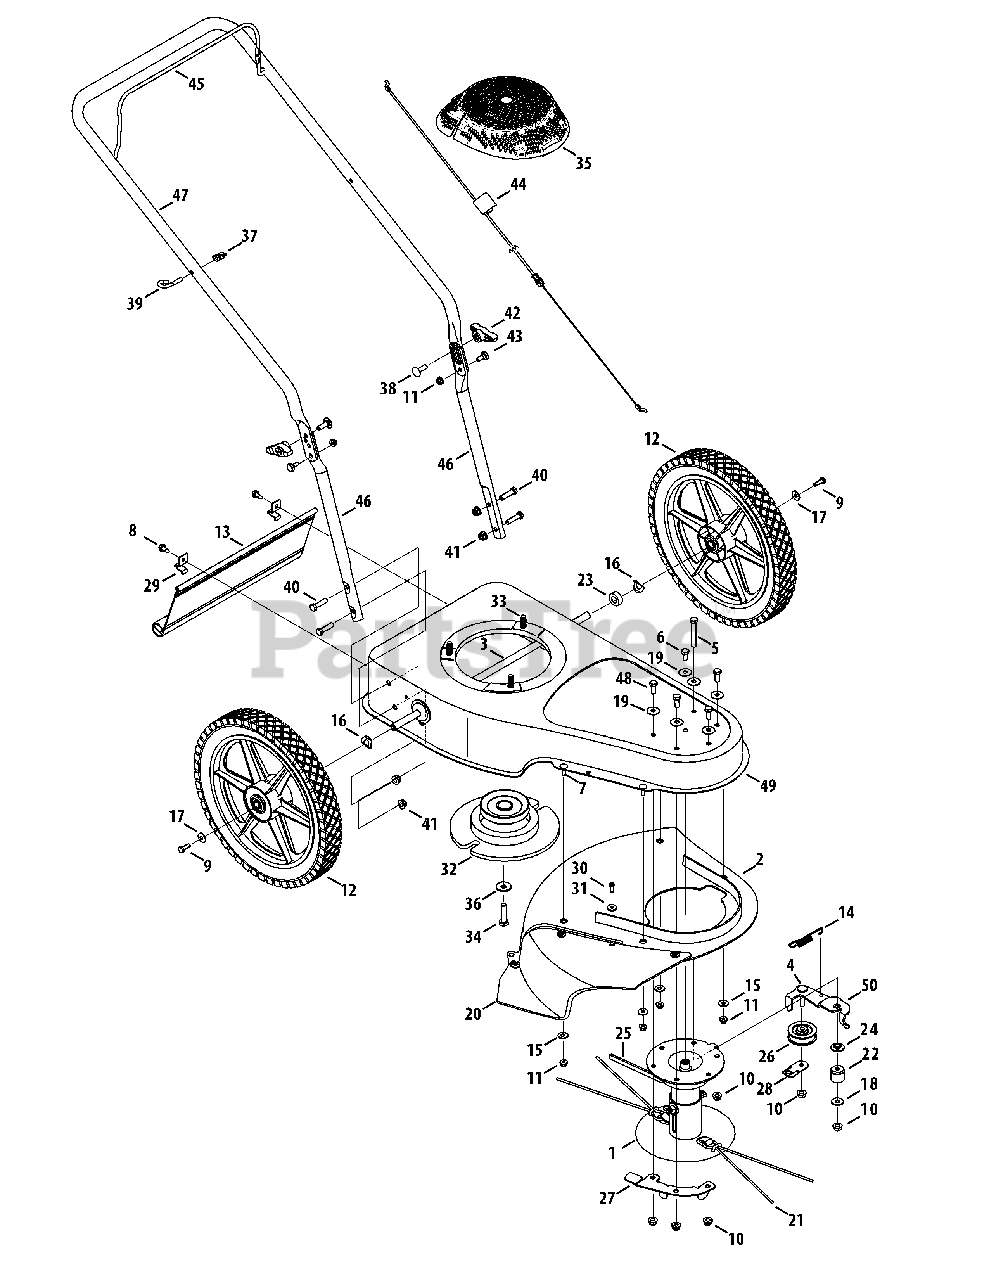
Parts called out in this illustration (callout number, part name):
1	Spindle Assembly
2	Deflector Assembly, Trimmer
3	Axle Assembly, Trimmer
4	Hex Cap Screw, 5/16-18 x 1.50
5	Hex Cap Screw, 5/16-18 x 2.25
6	Hex Screw, 5/16-24, .625, Gr5, Std
7	Screw, Carriage, 1/4-20, .75, Gr5
8	Screw, Self-tapping, 1/4-20 x .625
9	Hex Screw, 1/4-20, .75, Gr5, Std
10	Nut, Flange Lock, 5/16-18, GrF
11	Nut, Flange Lock, 1/4-20, GrF
12	Wheel, 14 x 1.75, Gray
13	Trailshield, 5.85 x 14.50
14	Spring, Extension, .50 OD x 3.375
15	Washer, Flat, .280 x .740 x .063
16	Washer, Spring, .500 x 1.00 x .022
17	Washer, Belle, .265 x .750 x .060
18	Washer, Flat, .343 x .880 x .062
19	Washer, Belle, .325 x .930 x .045
20	Flap, Deflector, String Trimmer
21	Line, Trimmer, .155, 10-pack
22	P/M Spacer
23	Spacer, .51 ID x 1.00 OD x .38
24	Spacer, Idler, Trimmer
26	Pulley, Idler, Trimmer
27	Keeper Bracket, Front
28	Keeper Bracket, Idler
29	Hinge Clip, Trailshield
30	Screw, HL, #12-16, .625, Panphi
31	Washer, Flat, .194 x .62 x .063
32	Pulley/Flywheel
33	Sems Screw, 3/8-16, 1.0,
34	Hex Screw, 3/8-24, 1.25, Gr8
35	Cover, Shroud
36	Washer, Belle, .396 x 1.14 x .095
37	Knob, Handle
38	Screw, Carriage, 5/16-18, 1.00, Gr5
39	Eye Bolt, 1/4-20
40	Hex Screw, 3/8-16, 1.25, Gr5, Std
41	Nut,, Flange Lock, 3/8-16, GRF
42	Knob, Wing, 5/16-18, Black
43	Shoulder Screw, .375 x .148 x1/4-20
44	Control Cable, 48"
46	Handle, Lower
47	Handle, Upper
48	Hex Cap Screw, 5/16-18 x .75
50	Idler Trimmer Bracket
